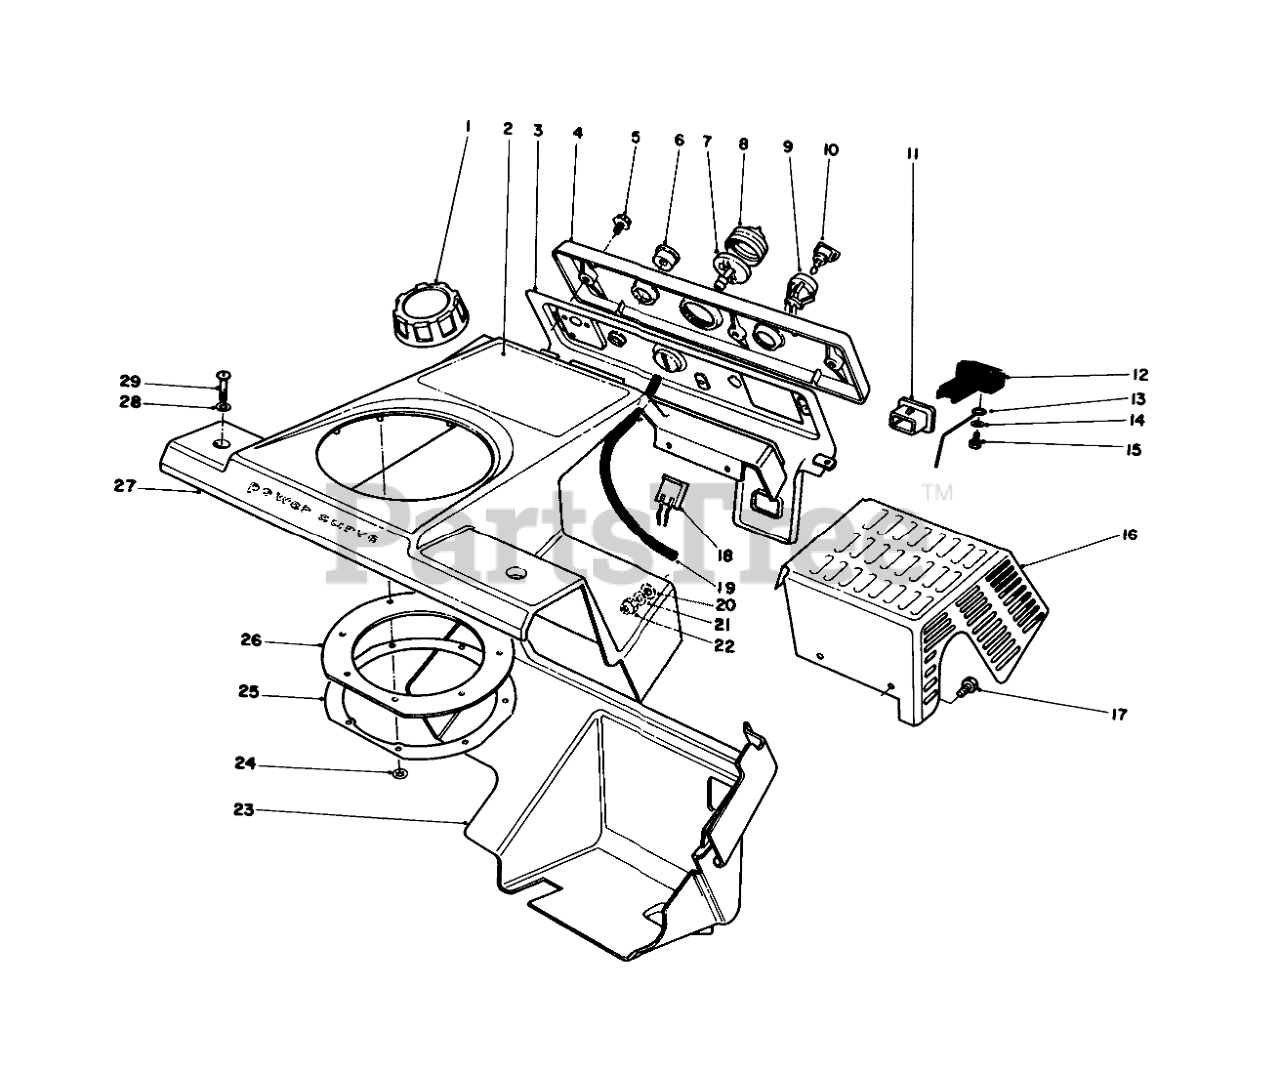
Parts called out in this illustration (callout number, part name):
1	CAP-FUEL ASM
2	DECAL - CCR 2000
3	Control Panel Assembly (Incl. Ref. #6-8 & 11)
4	CONTROL NAMEPLATE
5	SCREW
6	GUIDE-ROPE, STARTER
7	BODY-PRIMER
8	BULB-PRIMER
9	SWITCH
10	KEY-IGNITION
11	FITTING
12	CONTROL-CHOKE
13	Linkage-Choke
14	WASHER-PLAIN
15	#8 X .625" PHILPS PAN H
16	Wa-Shield
17	SCREW-SHH
18	CONNECTOR-BODY
19	PRIMER HOSE
20	WASHER
21	WASHER-FLAT
22	NUT-LOCK, NI
23	Shroud-Lower
24	PALNUT
25	Retainer-Chute Seal
26	SEAL-CHUTE
27	Upper Shroud Assembly (Incl. Ref. #2 & 24-26)
28	WASHER-FLAT
29	SCREW-PPH
